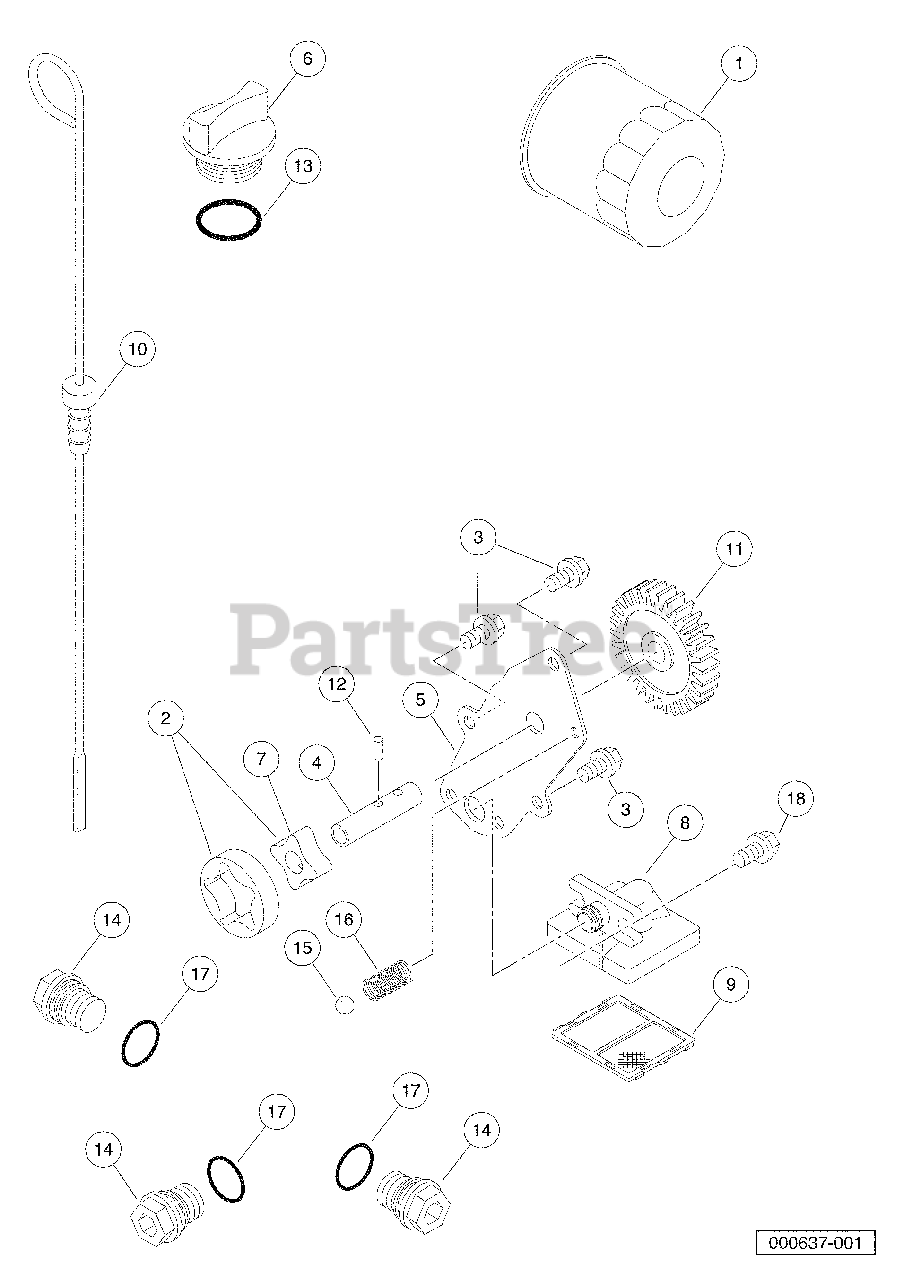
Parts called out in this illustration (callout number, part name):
1	Filter,Oil
2	OilPumpAndRotor
3	Bolt,Flg,M6X1.0X12
4	Shaft,OilPump,Fh
5	Plate,OilPump,Fh.
6	Cap,Oil,Fill,Fh
7	Rotor,Pump,Oil,In,Fh
8	Pickup,Oil,Fh
9	Screen,Pickup,Oil,Fh
10	Gauge,Oil,Fh
11	Gear,Spur,OilPump,Fh
12	Pin,OilPump,Fh.
13	O-ring,Cap,Oil,Fill,Fh
14	Plug,OilDrain,Fh
15	Ball,OilPump,Fh.
16	Spring,OilPump,Fh
17	O-ring,DrainPlug,Oil,Fh
18	Bolt,OilPickup,Fh
